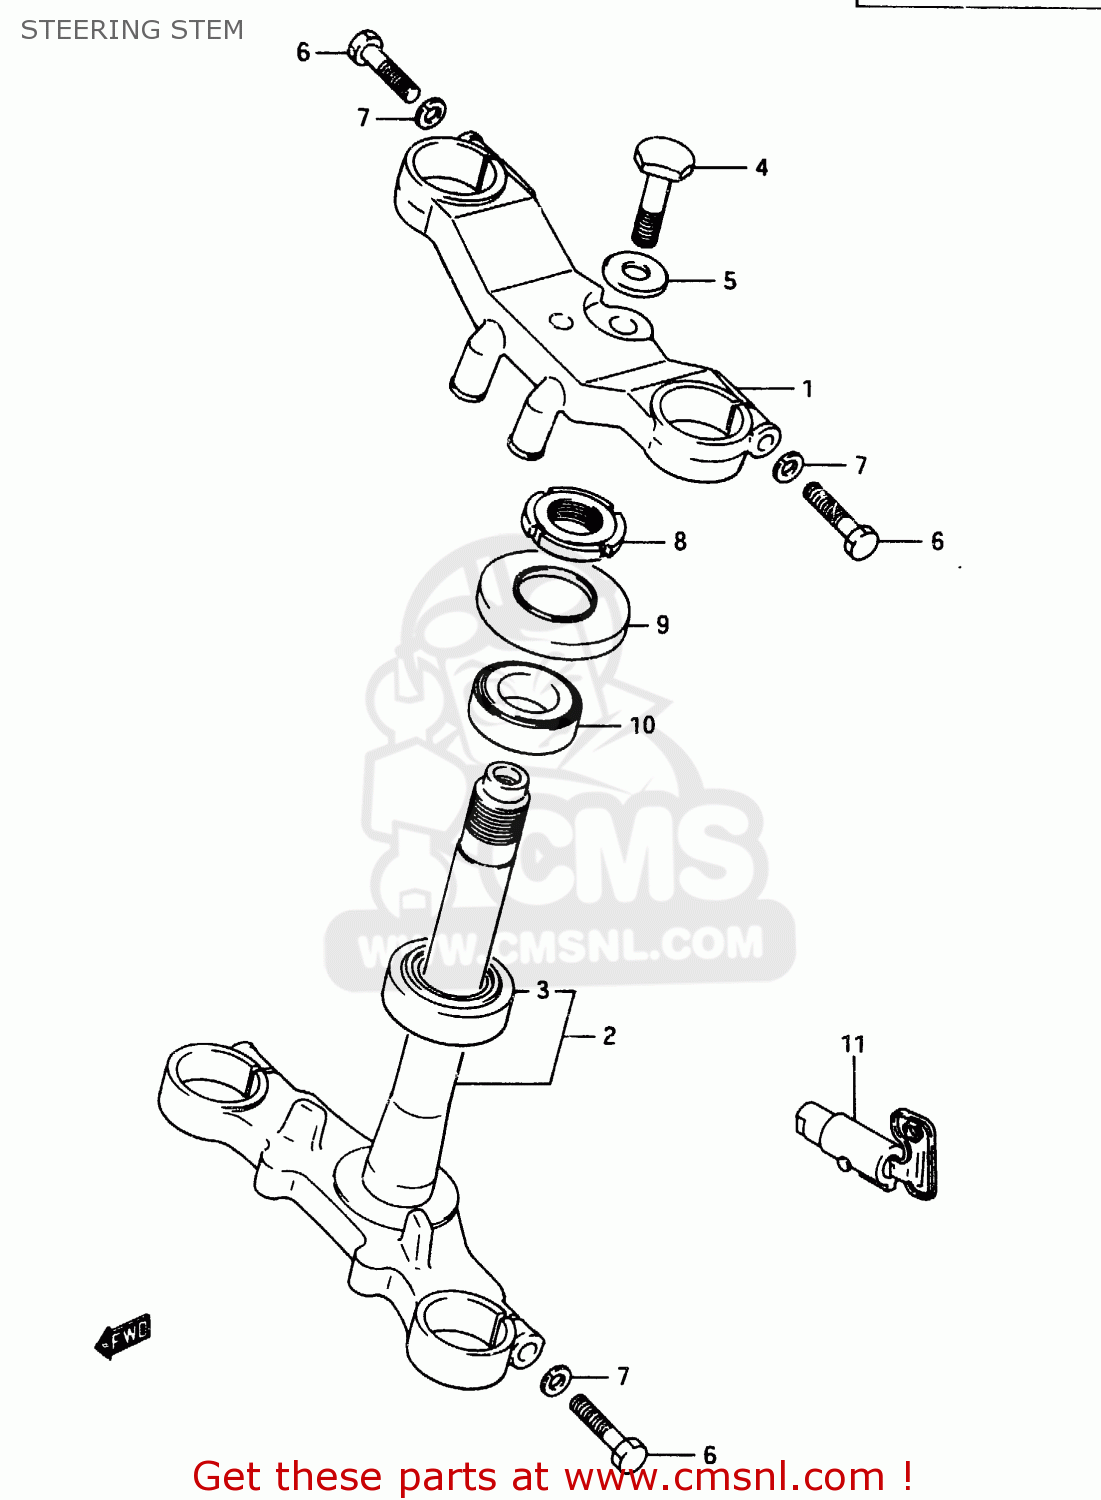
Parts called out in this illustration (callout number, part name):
1	STEM HEAD, STEERING (BLACK)
2	STEM, STEERING (BLACK)
3	BEARING
4	BOLT, STEERING SHAFT
5	WASHER
6	BOLT
7	WASHER,LOCK,8.
8	NUT,STEERING STEM(25X44X10)
9	SEAL OIL
10	TAPER,ROLLER BEARING
11	LOCK ASSEMBLY,STEERING (NEI
